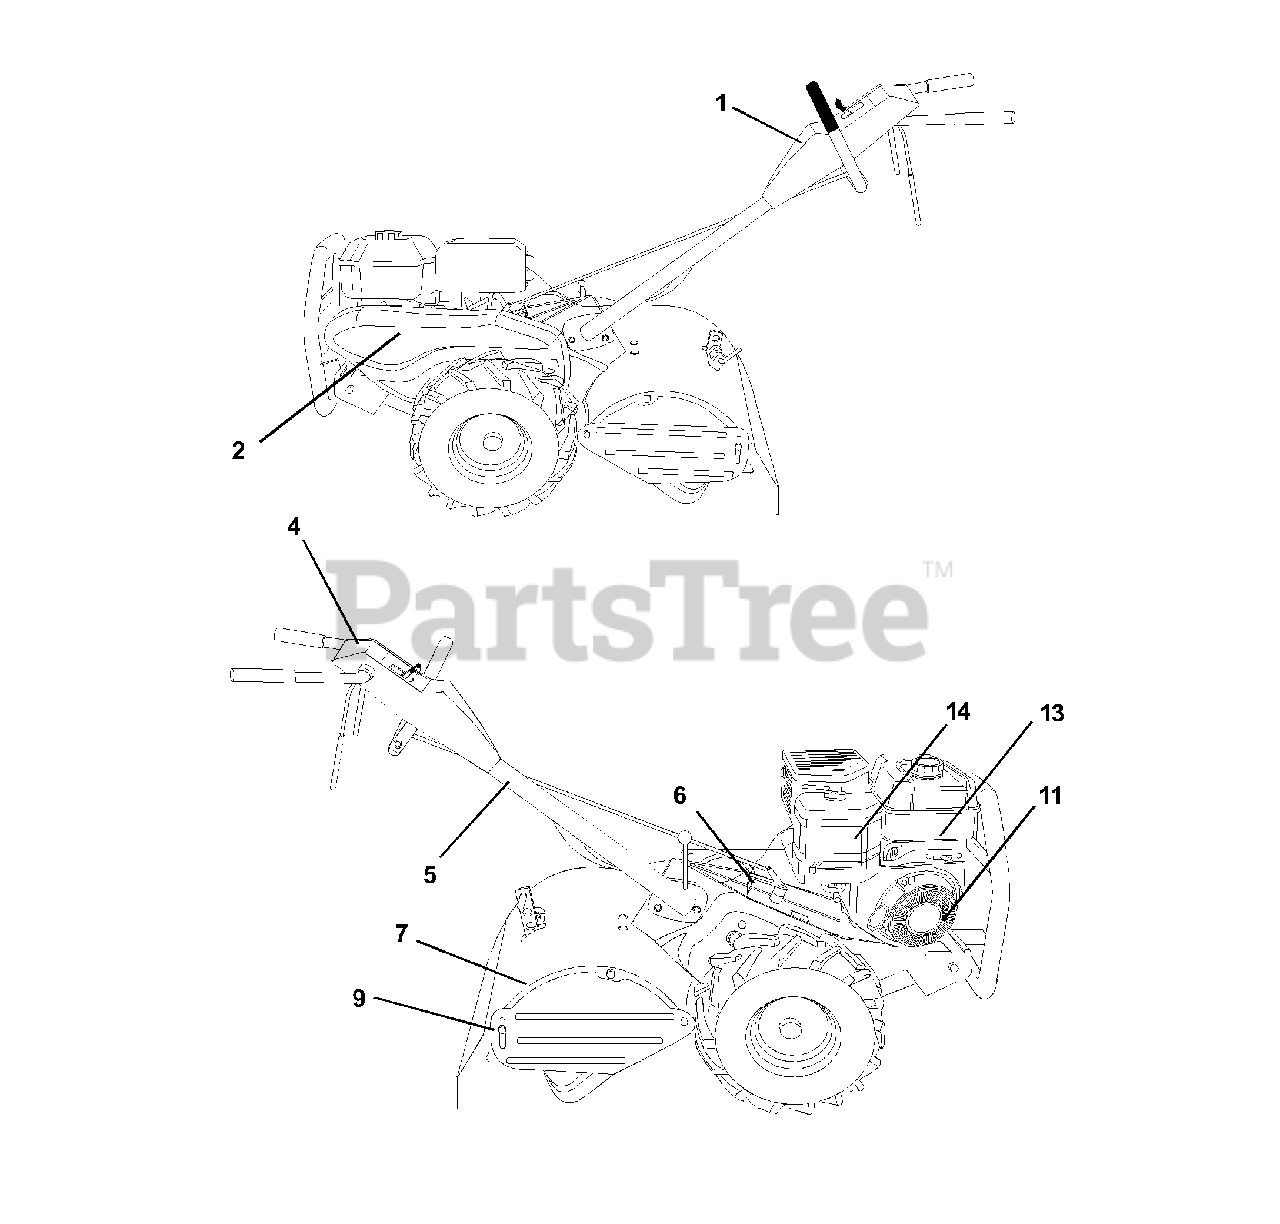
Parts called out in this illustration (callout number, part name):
1	Decal, Logo,CNTRL PNL
2	Decal, Logo, Belt Guard
4	Decal, Instruction, Tilling
5	Decal, Hand Placement
6	Decal, Shift Indicator
7	Decal, Caution
9	Decal, Warning, Rotating Tines
11	Decal, Rewind
13	Decal, B&S Tank
14	Decal, B&S Air Cleaner
